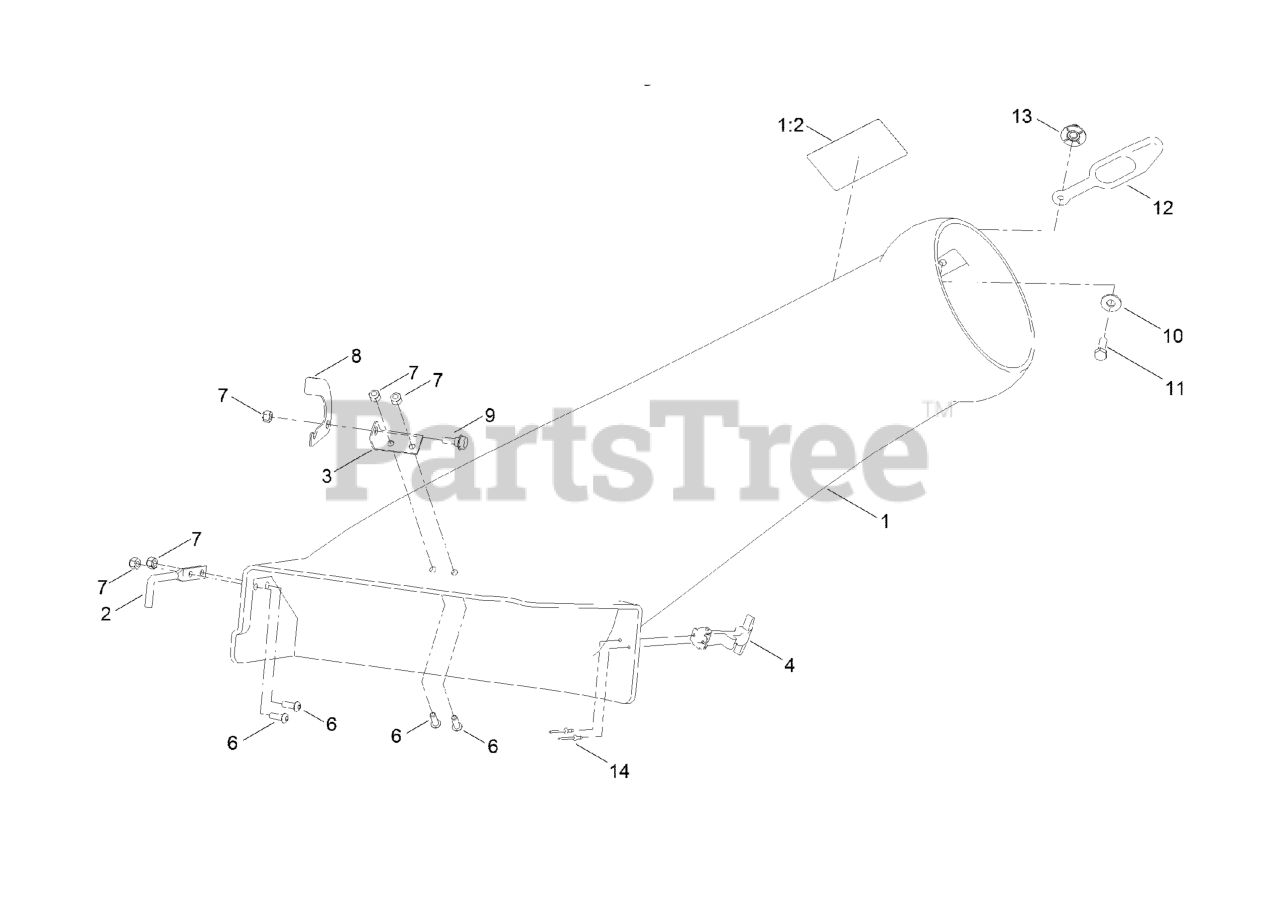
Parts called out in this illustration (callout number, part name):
1	50/54 Fab Bagger Boot
1:2	DECAL-DANGER
2	HOOK-BOOT
3	Plate-Pivot, Cz
4	HANDLE ASM
6	SCREW-HSBH
7	NUT-HEX
8	Plate-Latch
9	SCREW-SHOULDER, HHF
10	WASHER-FLAT
11	SCREW-HH
12	RETAINER-DUCT
13	NUT-IMPELLER
14	RIVET-POP
